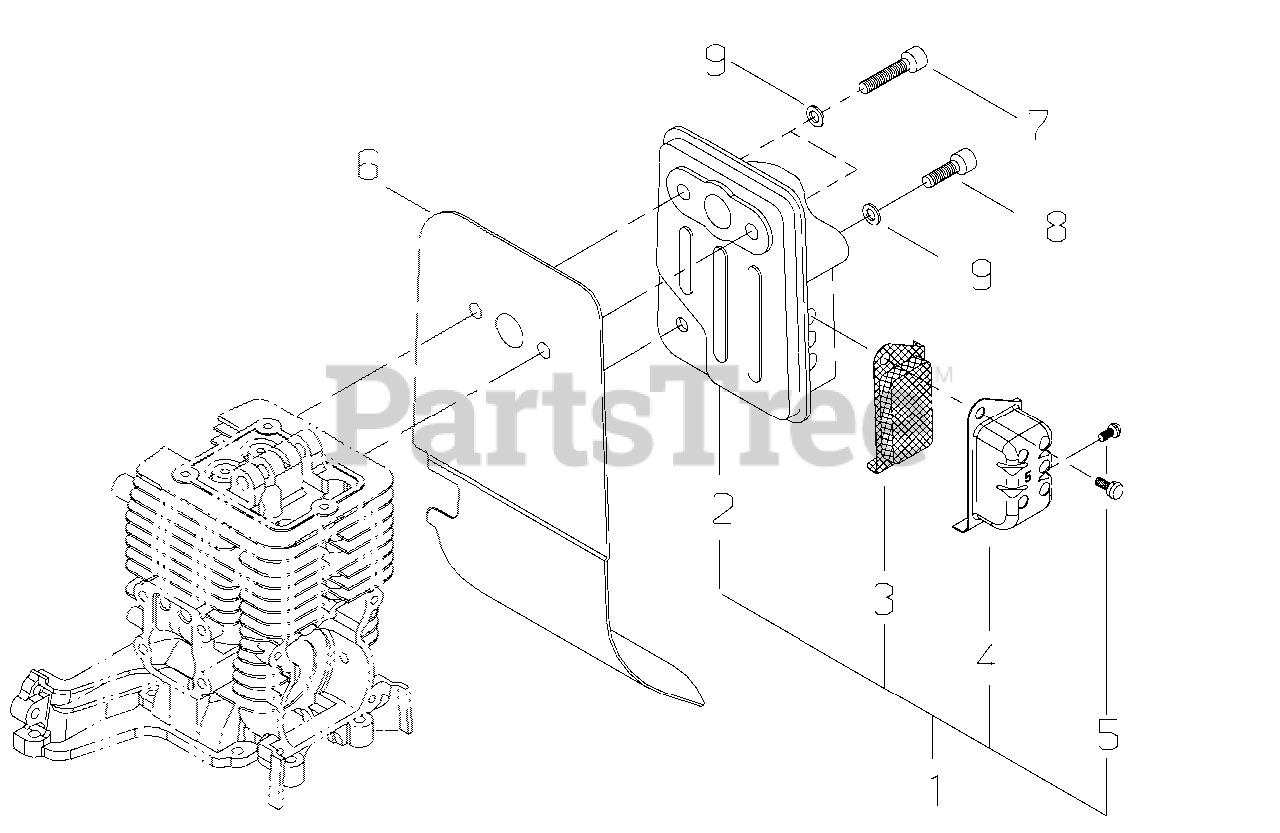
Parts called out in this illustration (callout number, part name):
1	MUFFLER ASSY
2	MUFFLER
3	SCREEN, SPARK ARRESTER
4	GUIDE, EXHAUST
5	SCREW M4×6
6	HEAT SHIELD, EXHAUST
7	BOLT M5×25
8	BOLT 5×16
9	WASHER, FLAT 5.5×10×0.8
